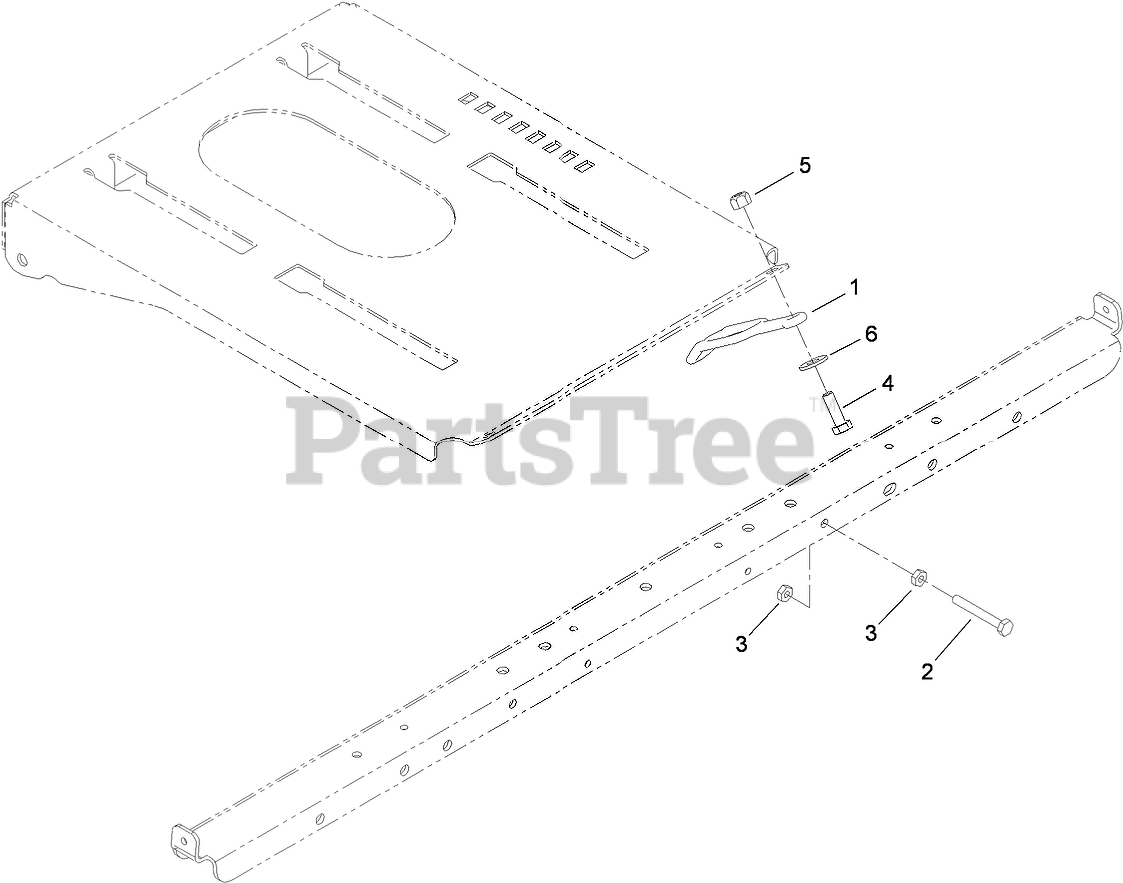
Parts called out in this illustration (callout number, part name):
1	RETAINER-DUCT
2	SCREW-HH
3	NUT-JAM
4	SCREW-HH
5	NUT-LOCK, NI
6	WASHER-FLAT
